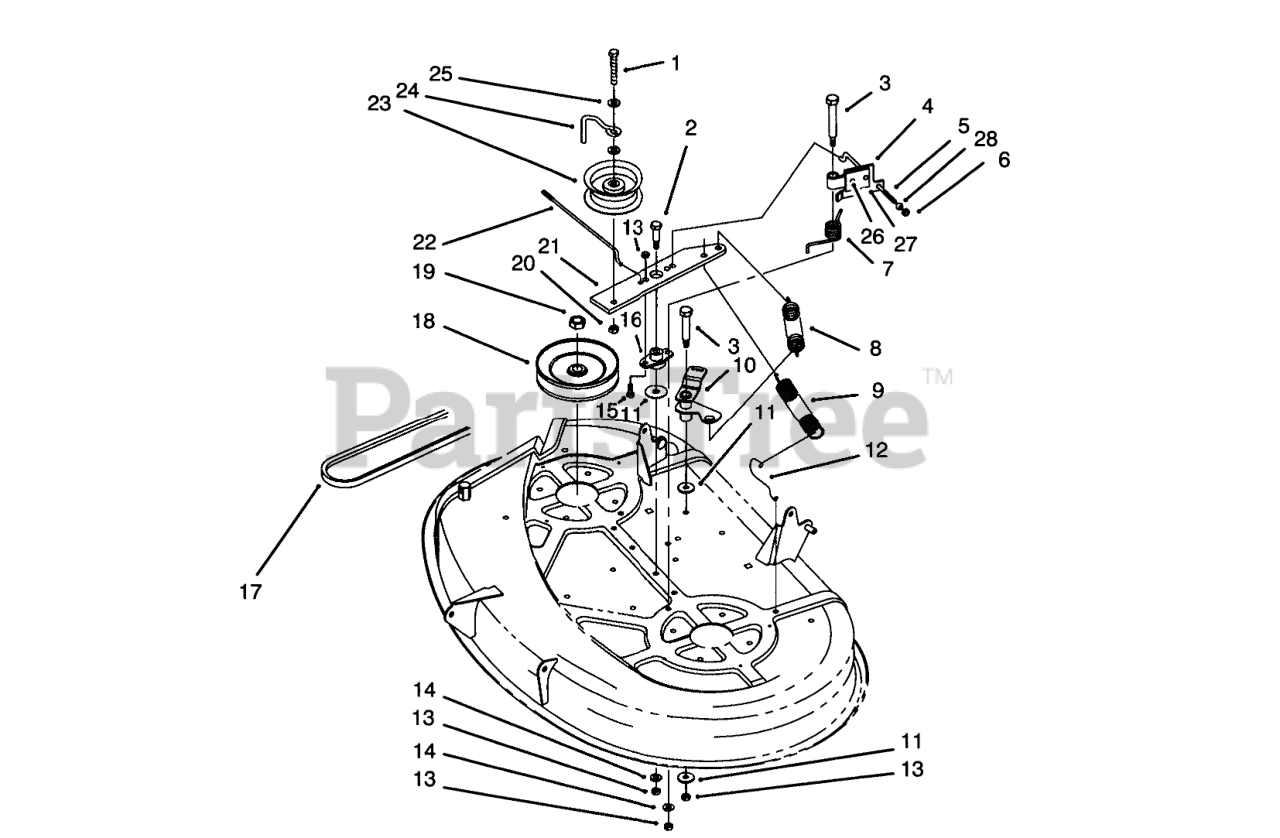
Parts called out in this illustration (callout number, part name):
1	SCREW-HH
2	SCREW-SHOULDER, HH
3	BOLT-SHOULDER
4	Brake-Deck (Incl. Ref. #26 & 27)
5	ROD-BRAKE, DECK LH
6	NUT-LOCK, NI
7	SPRING-TORSION
8	SPRING-DECK, ENGAGEMENT
9	SPRING-EXTENSION
10	Bellcrank
11	WASHER-FLAT
12	HOOK-RETURN, SPRING
13	NUT-LOCK, NI
14	WASHER-PLAIN
15	SCREW-HH
16	BUSHING-ARM, IDLER
17	BELT-V
18	PULLEY
19	NUT-HEX
20	NUT-LOCK, NI
21	Arm-Idler
22	ROD-BRAKE, DECK RH
23	PULLEY-IDLER, FLAT
24	GUIDE-IDLER, BELT
25	WASHER-FLAT
26	RIVET-BLIND
27	PAD-BRAKE
28	BALL-SWIVEL, STOP
